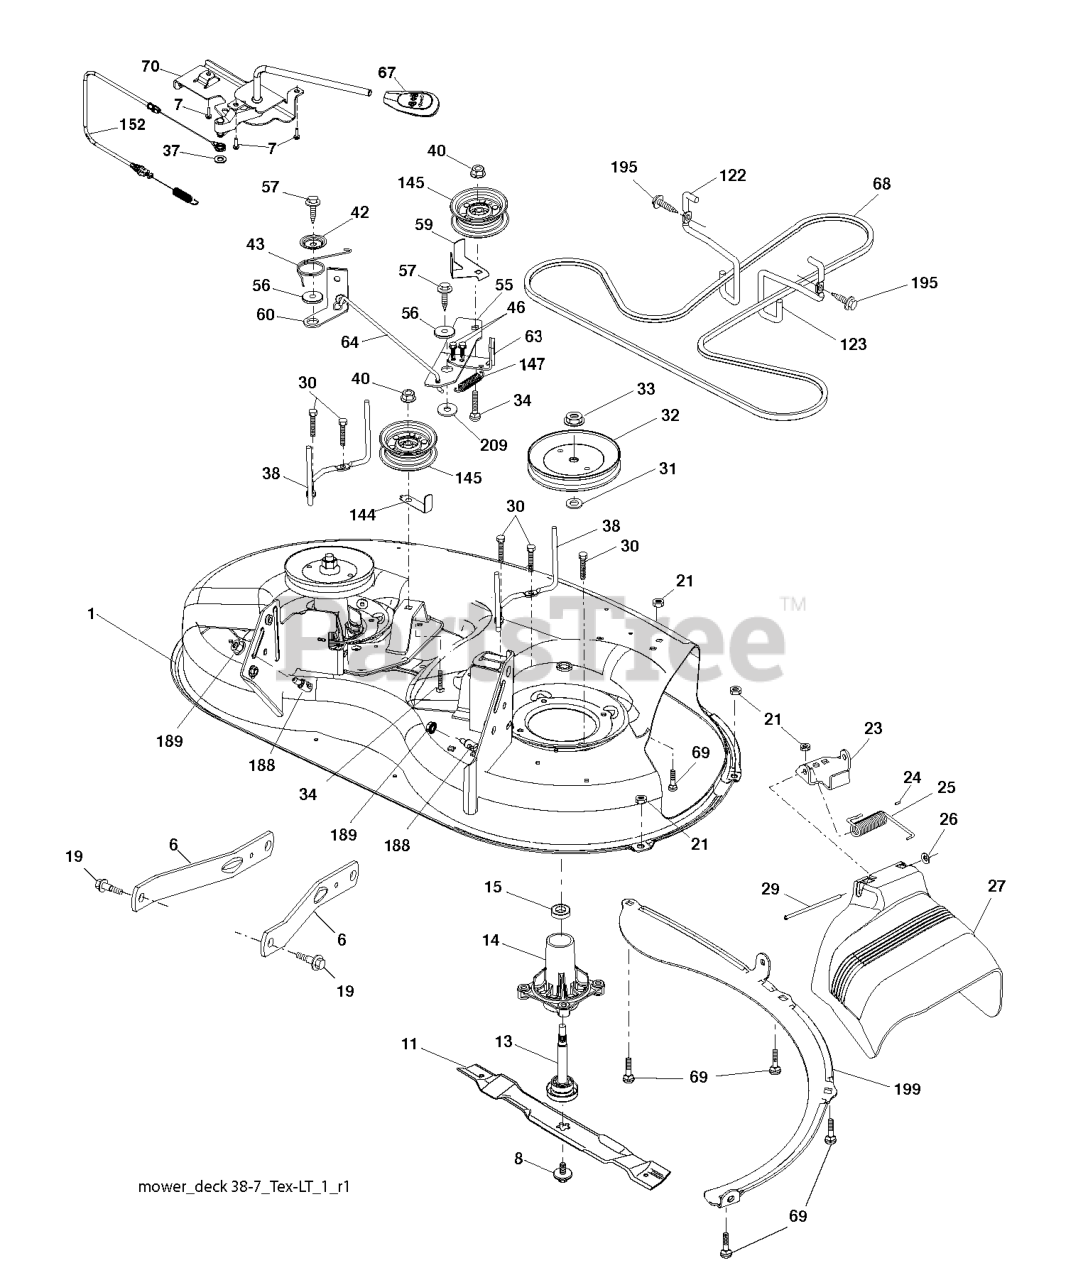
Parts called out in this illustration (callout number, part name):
1	HOUSING
6	ARM.SUSPENSION.MOWER.R
7	SCREW.#10 X 0.750.BOS
8	BOLT.WASHER.ASM.7/16-2
11	BLADE 38" PREMIUM
13	SHAFT.ASM.MDRL.N/GREASE.38
14	RP.HOUSING.MANDREL.4PT.
19	BOLT.SHOULDER
21	LOCKNUT
23	BRKT.DEFLECTOR.38"2005+
24	CAP-SLEEVE LT
25	SPRING.TORSION.DEFLECT
26	NUT PUSH M
27	SHIELD.DEFLECTOR.MWR.38-7/97CM
29	ROD.HINGE
30	SCREW, WASHER HEAD
31	WASHER.SPACER.MANDREL
32	PULLEY.MANDREL.5.0.PD.38"
33	NUT.FLANGE.LOCK.TOP
34	BOLT.3/8-16X1.50
37	WASHER
38	KEEPER BELT LH MANDREL
40	NUT LOCK FLG 3/8-16 UNC
42	SPRING.TORSION.BRAKE
43	SRPING.TORSION.RETAINE
46	SCREW.1/4-20X5/8
56	SPACER.RETAINER
57	SCREW 3/8-16X1
59	GUARD, BELT
60	ARM BRAKE MOWER RH 38"
63	RP ARM.BRAKE.MOWER.38"LH.TEX
64	LINK BRAKE
67	HANDLE.CLUTCH.CABLE.LT
69	BOLT
70	CLUTCH.ASM.MANUAL.LT.PRED
122	KEEPER BELT ENGINE LH
123	KEEPER BELT RH
144	KEEPER BELT
145	PULLEY.IDLER.48"PRIMARY
147	SPRING RETURN
152	CLUTCH CABLE
188	STUD.FASTNER.W/ANTI-ROTATE
189	NUT LOCK HEX FLANGE 5/16-18
195	SCREW, 3/8-16X3/4
199	BAFFLE.VORTEX.FRONT.38"
209	WASHER 12/32X2X10GA
